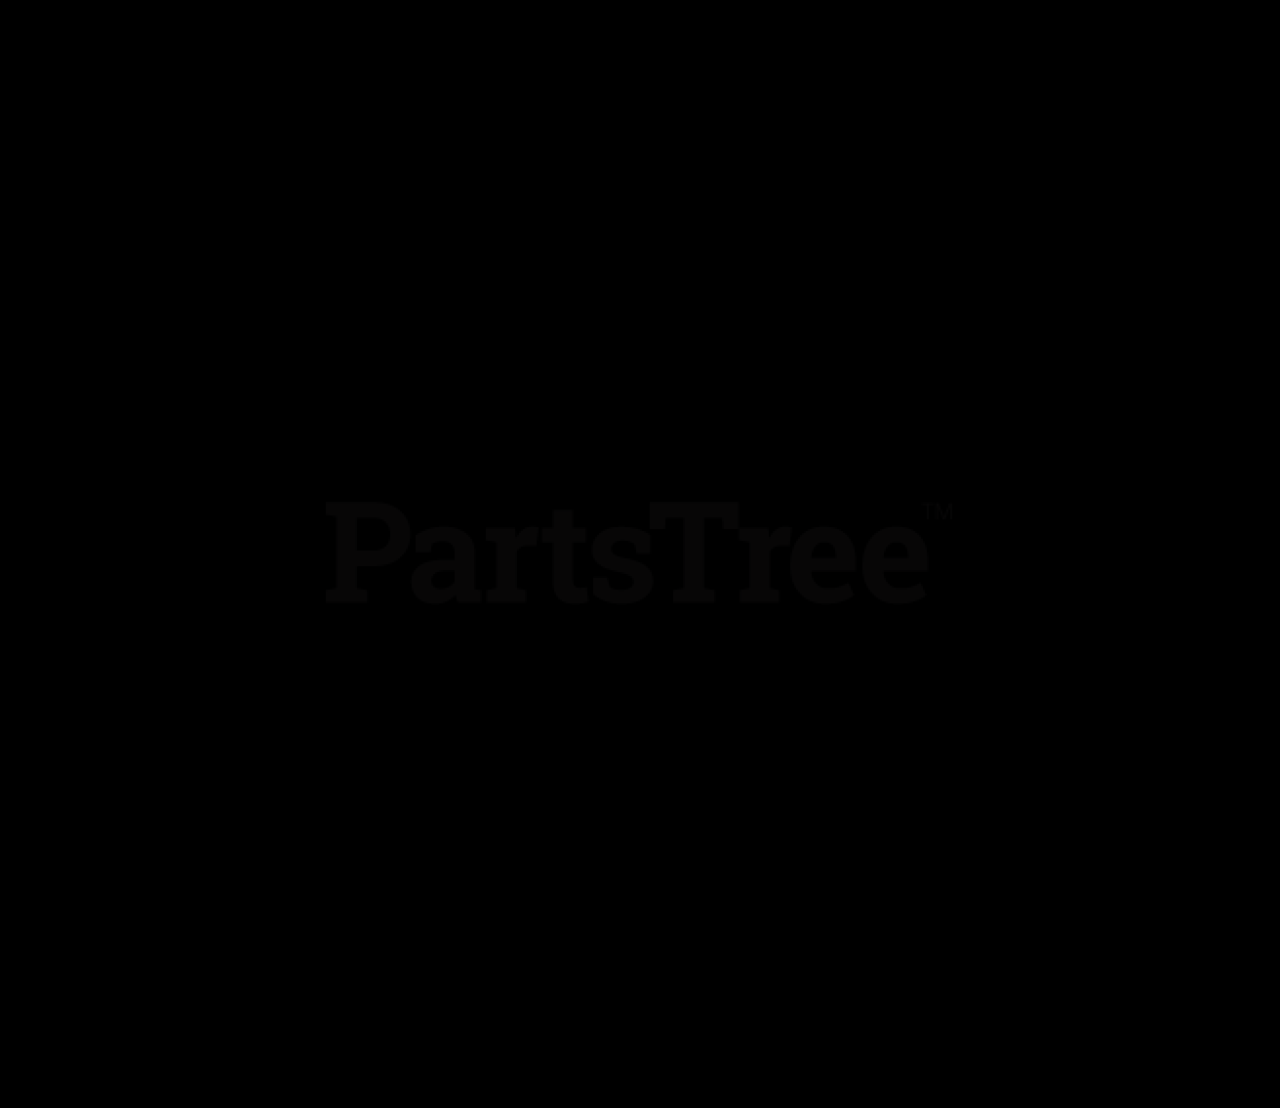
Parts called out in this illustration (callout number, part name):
1	Tank, Fuel - Right Hand
2	Bolt, Hex .31-18 x .75 Grade 5
3	Washer, Locking .31 x .078
4	Washer, Flat Steel .38 x .875 x .083
5	Gas Line, Bulk .25 I.D. (2 @ 63 in.)
6	Clamp, Hose Wire .49/.51 x .116
7	Tank, Left Hand Fuel (EYE-Q)- 200 Series
8	Valve, Fuel
9	Cap, Gas
11	Tank Fitting
